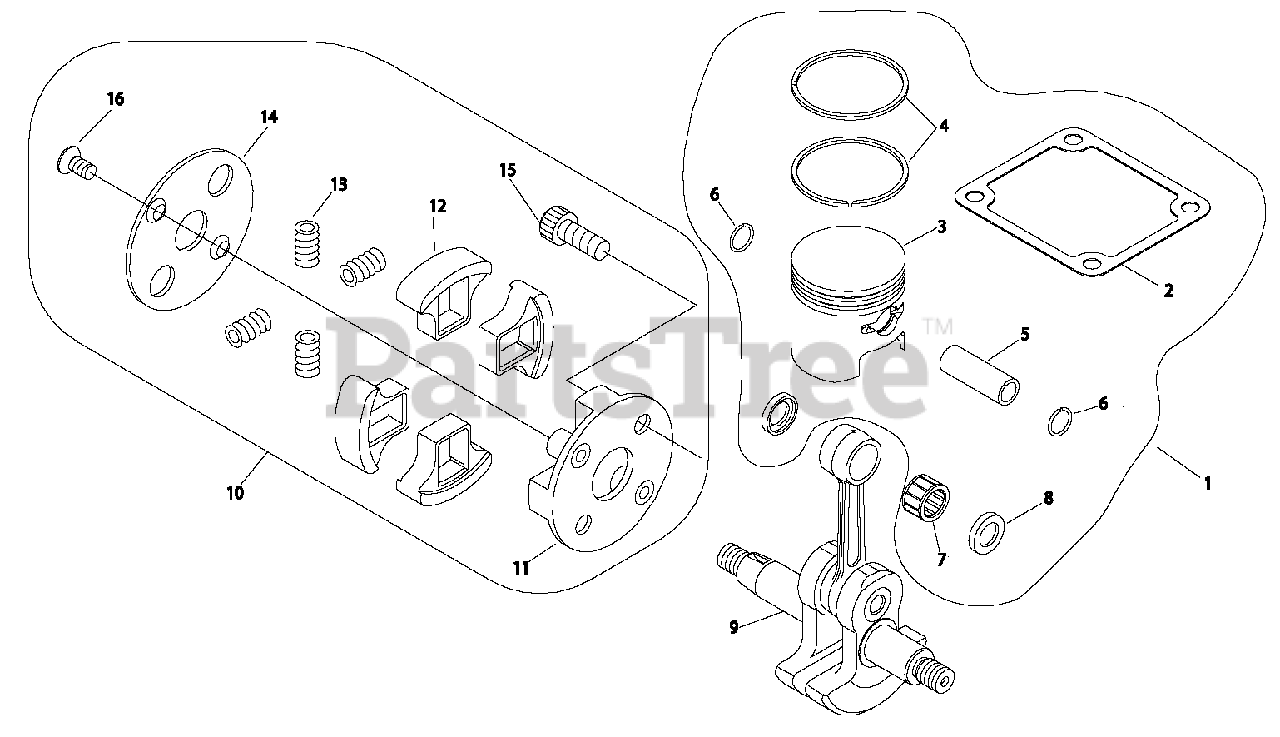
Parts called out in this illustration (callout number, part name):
1	PISTON KIT
2	GASKET, CYLINDER
3	PISTON
4	RING, PISTON
5	PIN, PISTON 10
6	RING, SNAP
7	BEARING, NEEDLE 10
8	WASHER, THRUST
9	CRANKSHAFT ASSY
10	CLUTCH ASSY
11	BOSS, CLUTCH
12	SHOE, CLUTCH
13	SPRING, CLUTCH
14	PLATE, CLUTCH
15	BOLT, CLUTCH
16	BOLT 5
